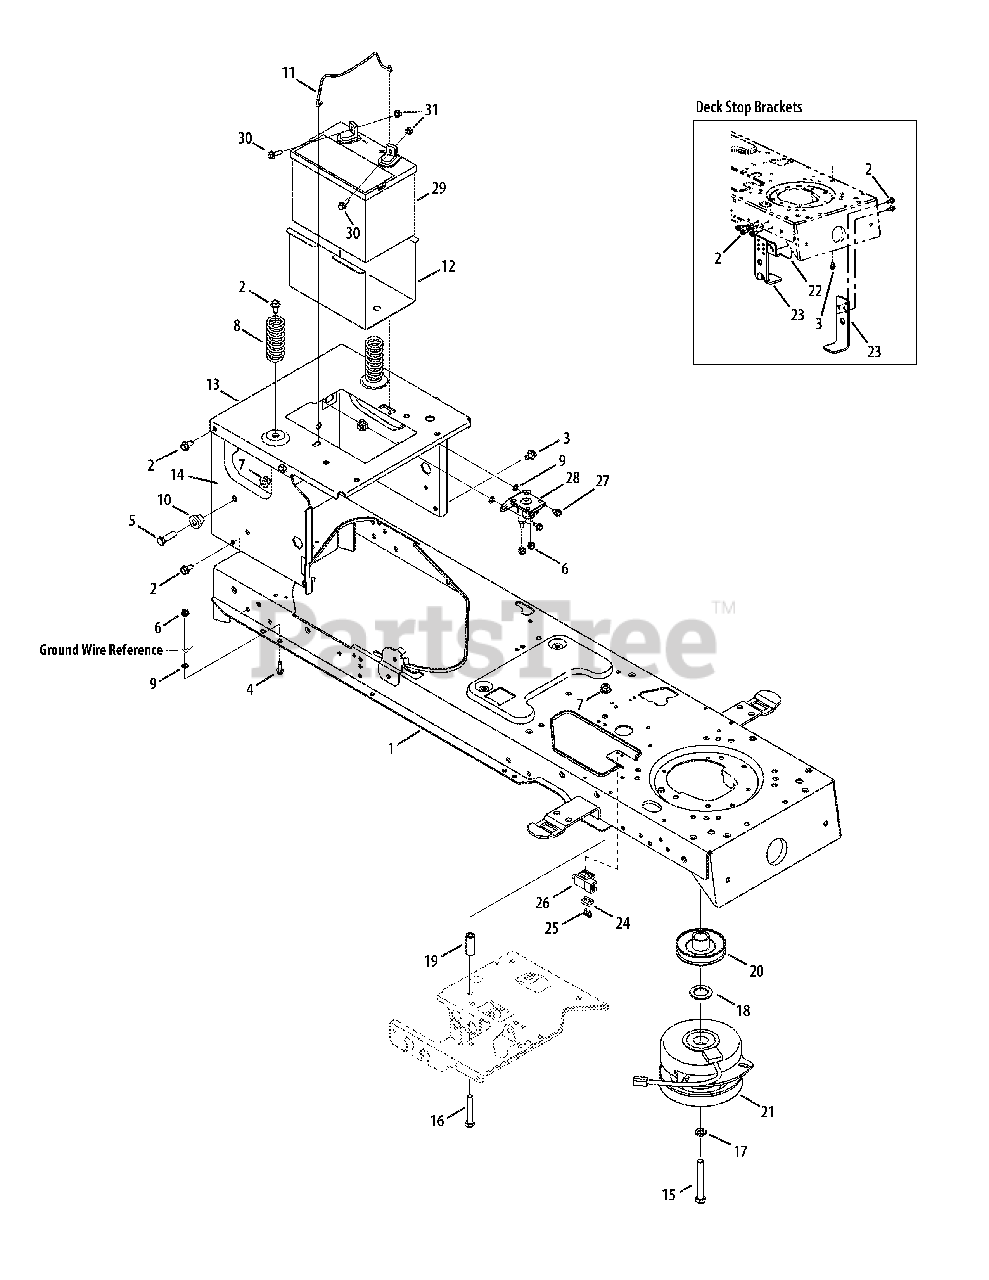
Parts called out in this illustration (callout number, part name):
1	Frame Assembly, Lower
2	Screw, 5/16-18 x 0.75
3	Screw, 5/16-18, 0.500
4	Screw, 1/4-20, 0.750
5	Screw, 3/8-16, 1.25, Gr5
6	Nut, Flange Lock, 1/4-20
7	Nut, Flange Lock, 3/8-16
8	Spring, Compress., 1.28 x 3.125
9	Washer, Lock, 1/4, External
10	Spacer, Shoulder,.38 x 1.0 x.70
11	Hold Rod, Battery
12	Battery Tray
13	Seat Bracket, Frame
14	Frame, Upper
15	Screw, 7/16-20, 3.50, Gr5, Lock
16	Screw, 3/8-16, 2.25, Gr5
17	Lock Washer, 7/16
18	Washer, Flat, 1.031 x 1.620 x.095
19	Spacer,.385 ID x.635 OD x 1.54
20	Pulley, Engine, 3.56 Diameter
21	PTO Clutch, Electric (50" Deck Units)
22	Clutch Bracket
23	Deck Bracket, Up-Stop (50" Deck)
24	Switch Plate
25	AB Screw, #10-16 x.500
26	Switch
27	Screw, 1/4-20, 0.50
28	Solenoid, 12V, 100 Amp
29	Battery, 245 CCA
30	Hex Flange Bolt, 1/4-20,.75
31	Nut, Sems, 1/4-20
